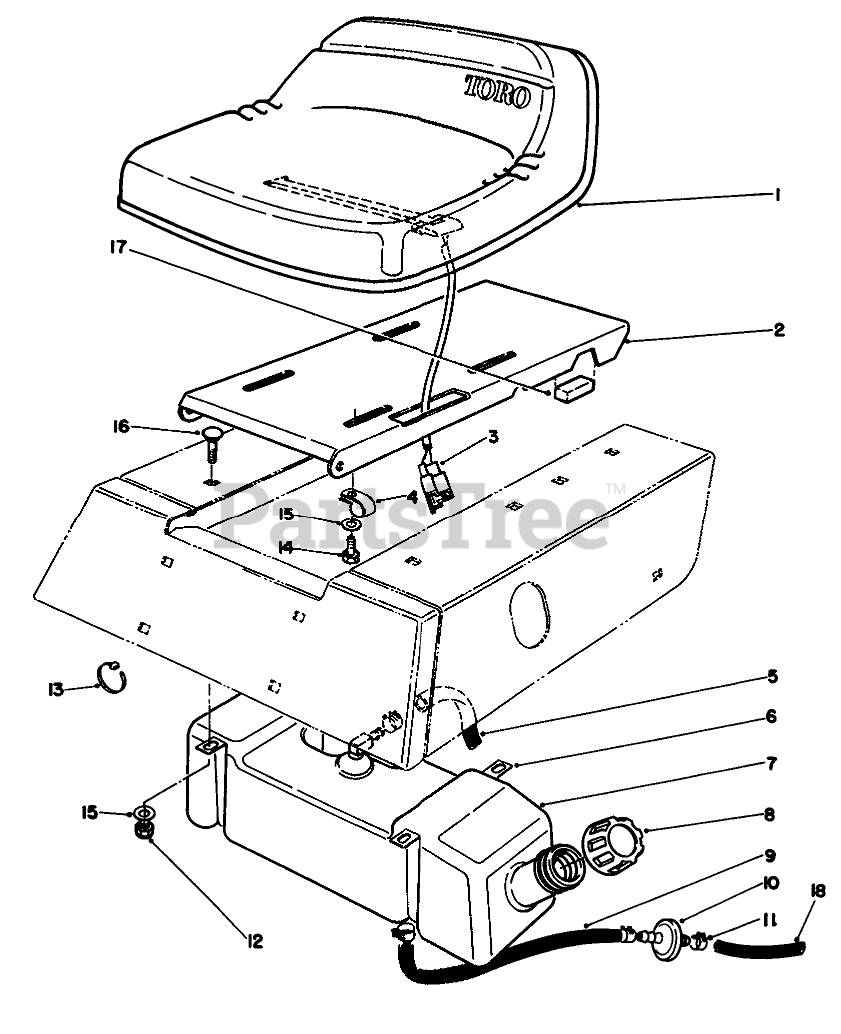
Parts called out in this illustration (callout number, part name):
1	Seat
2	BASE - SEAT
3	SWITCH-SEAT
4	CLIP-FUEL LINE
5	HOSE-FUEL
6	STRAP-GAS TANK
7	TANK-GAS
8	GAS CAP ASM
9	HOSE-FUEL
10	FILTER-FUEL
11	CLAMP-HOSE
12	NUT-LOCK, NI
13	TIE-CABLE
14	SCREW-HH
15	WASHER-PLAIN
16	SCREW-CARR
17	PAD-ISOLATOR
18	HOSE-FUEL
